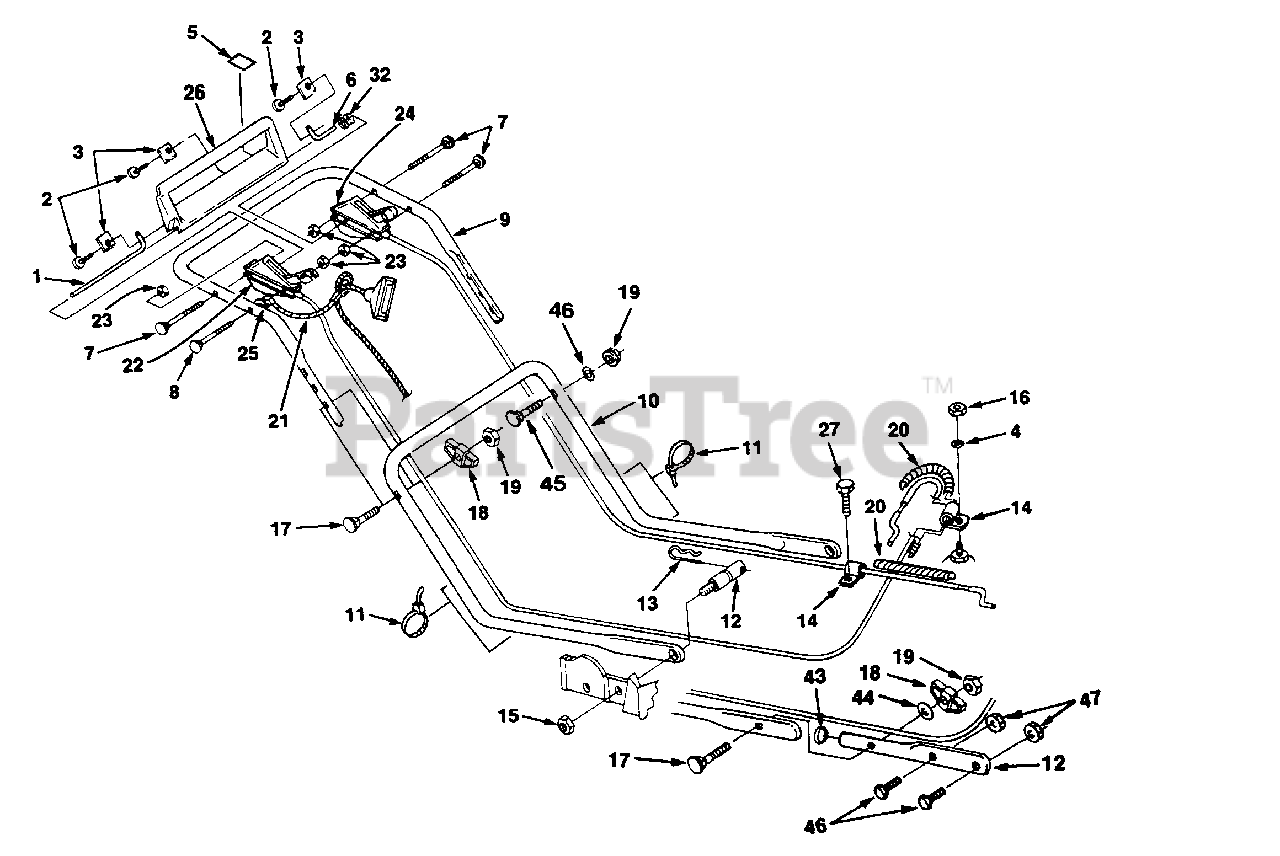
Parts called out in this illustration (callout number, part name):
2	SCREW - 1/4 - 10 x 5/8
3	CLAMP - Pivot shaft
4	WASHER, LOCK
5	DECAL- Warning
6	SHAFT - Pivot
7	BOLT- Sq. neck
8	BOLT- Sq. neck
9	HANDLE- Upper
11	CABLE - Tie
12	Stud - handle mounting
15	HEX WASHER NUT-TBO
18	HANDLE KNOB-TBO
19	NUT TBO
20	COVER - Cable
21	ROPE- Restraint
22	ENGINE - Control
23	NUT-Lock (1/4-20)
24	CONTROL- Throttle
26	BAIL- Brake control
27	SCREW- 1/4-20 x 5/8"
32	SPRING - Compression
